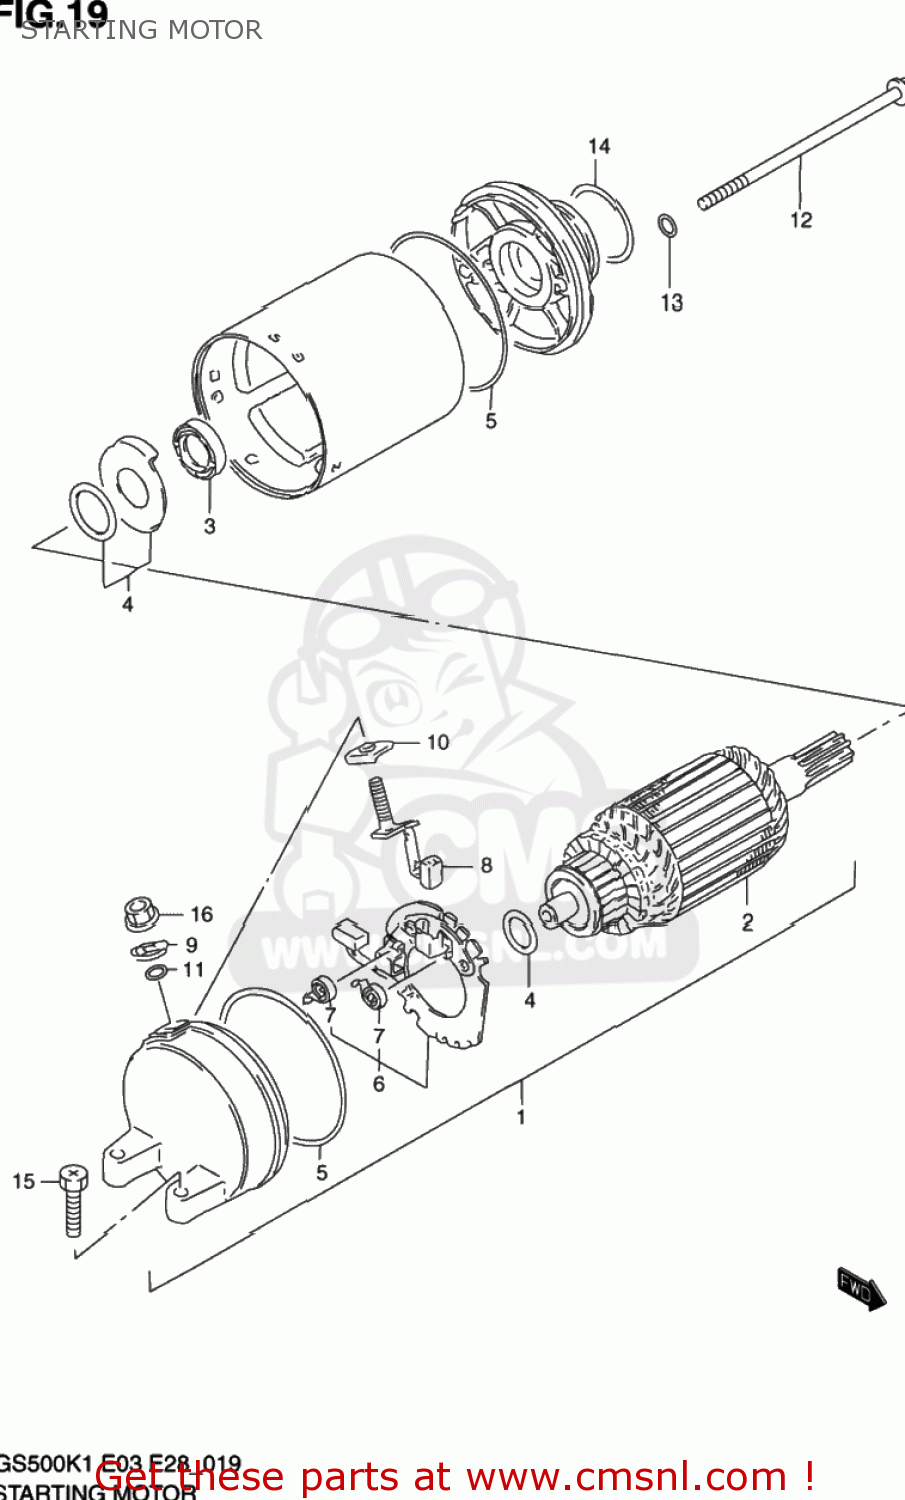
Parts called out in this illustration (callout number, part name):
1	MOTOR ASSEMBLY,STARTING
2	ARMATURE
3	SEAL,OIL
4	SHIM SET,STARTING MOTOR
5	O RING
6	HOLDER,BRUSH
7	SPRING
8	BRUSH SUB ASSY,STARTING MOTOR
9	BUSHING
10	BUSH,B
11	O RING
12	BOLT
13	O RING
14	O RING(D:3,ID:24.5)
15	SCREW (6X25)
16	NUT
